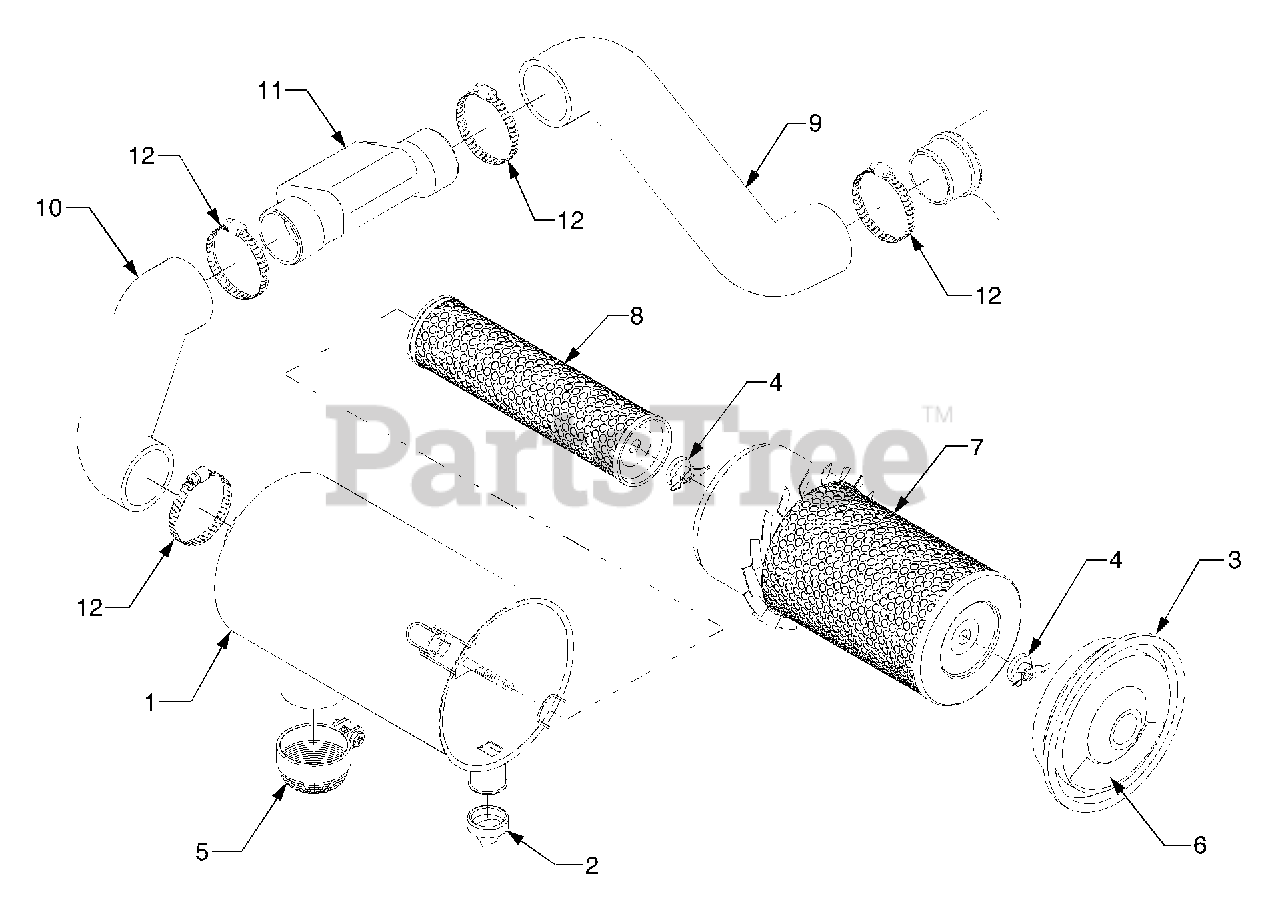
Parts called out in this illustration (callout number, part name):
1	Aircleaner Body Ass'y
3	Cover, Aircleaner
7	Element1, Aircleaner
8	Element2, Aircleaner
9	Pipe 1, Inlet
10	Pipe 2, Inlet
11	Pipe 3, Inlet
